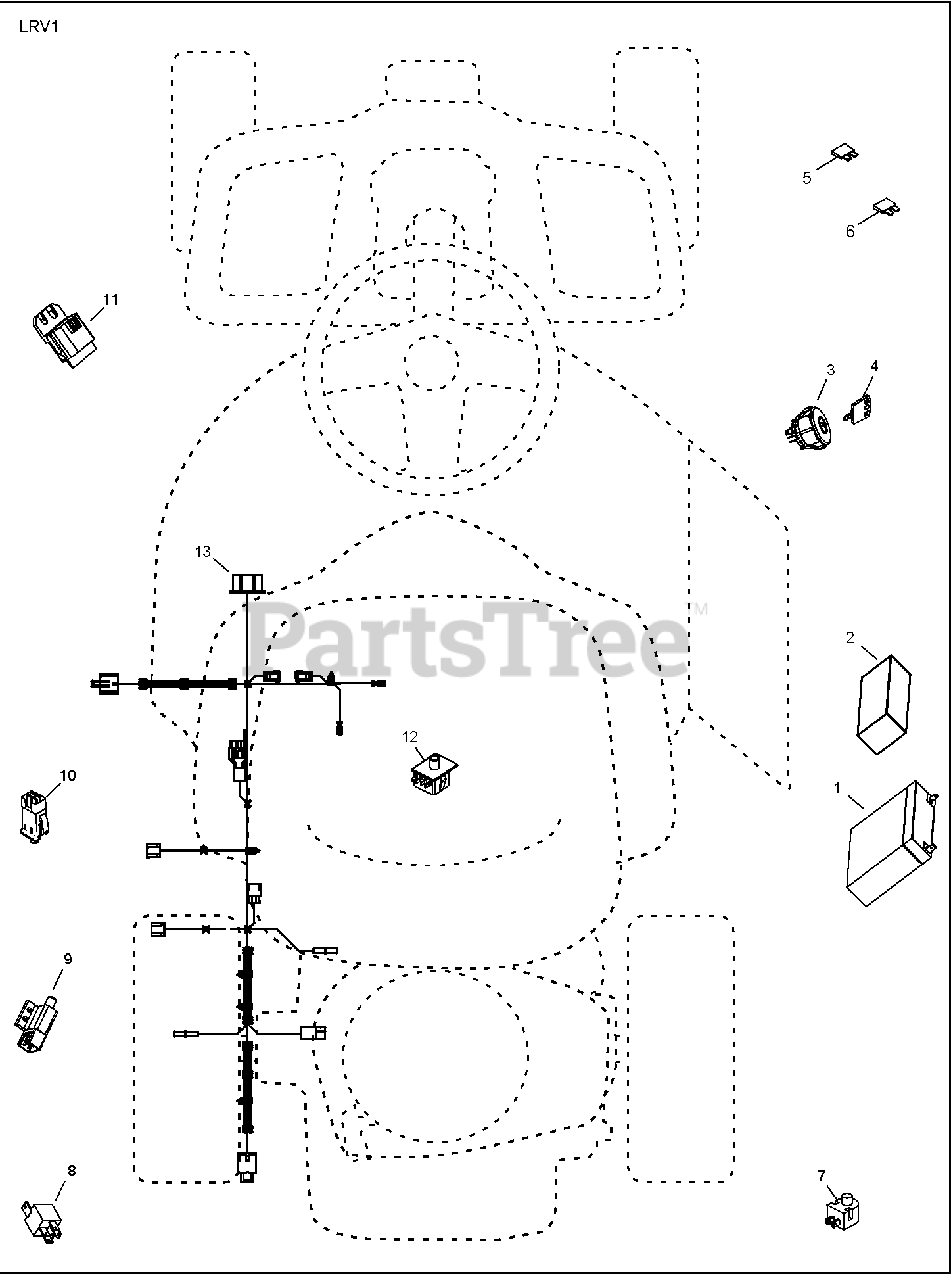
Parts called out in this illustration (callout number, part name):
1	BATTERY, 12V, 8AH
2	FOAM, POLYURETHANE
3	SWITCH, IGN, DLTA, P-IN, ROS
4	KEY, MOLDED
5	FUSE, 5A
6	FUSE, 40A
7	SWITCH, PLUNGER, NO, OLIVE
8	RELAY, 40A
9	SWITCH, INTLK,CL, MWR, GRY
10	SWITCH, INTERLOCK, NONC,GRAY
11	MODULE, STARTING, RECOIL, LRV
12	SWITCH, SEAT, DP, ROS
13	HARNESS, IGN, ELECTSTART, LRV
